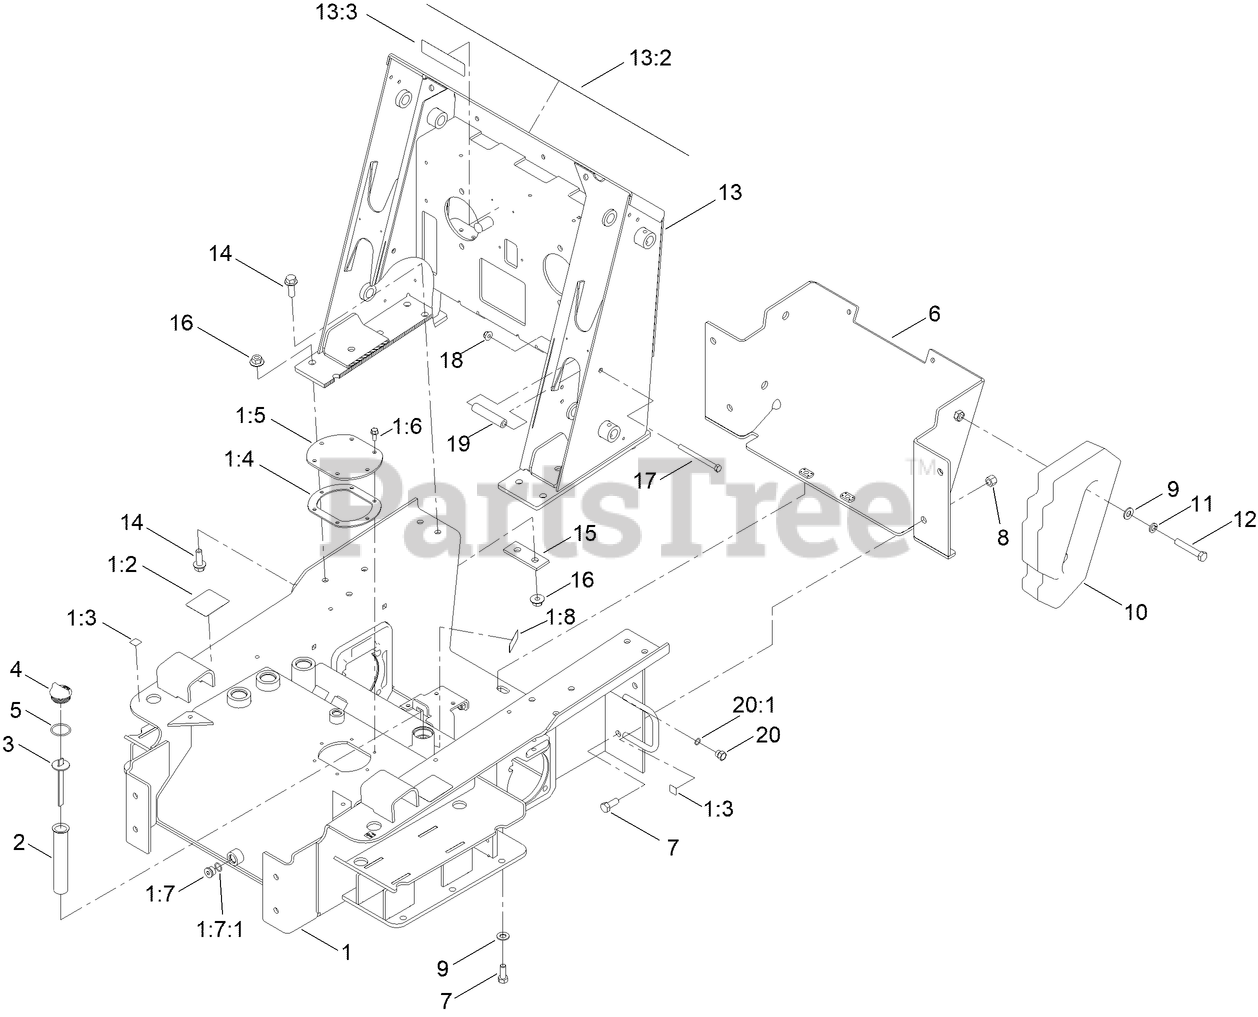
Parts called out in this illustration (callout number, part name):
1	CHASSIS ASM
1:2	DECAL-WARNING
1:3	DECAL-POINT, LIFT
1:4	GASKET-COVER, ACCESS
1:5	COVER-TANK
1:6	SCREW-HHF
1:7	PLUG-HEX
1:7:1	O-RING
1:8	DECAL-OIL, HYD
2	FILTER-SCREEN
3	DIPSTICK-OIL
4	PLUG-PLASTIC
5	O-RING
6	COVER-REAR
7	SCREW-HH
8	NUT-LOCK, NI
9	WASHER-FLAT
10	COUNTERWEIGHT-REAR
11	WASHER-LOCK
12	SCREW-HH
13	LOADER TOWER ASM
13:2	DECAL-PANEL, CONTROL
13:3	DECAL-DANGER
14	SCREW-HHF
15	PLATE-STIFFENER
16	NUT-LOCK, FLANGE
17	SCREW-HH
18	NUT-HF, NI
19	TUBE-SPACER
20	PLUG-HH
20:1	O-RING
